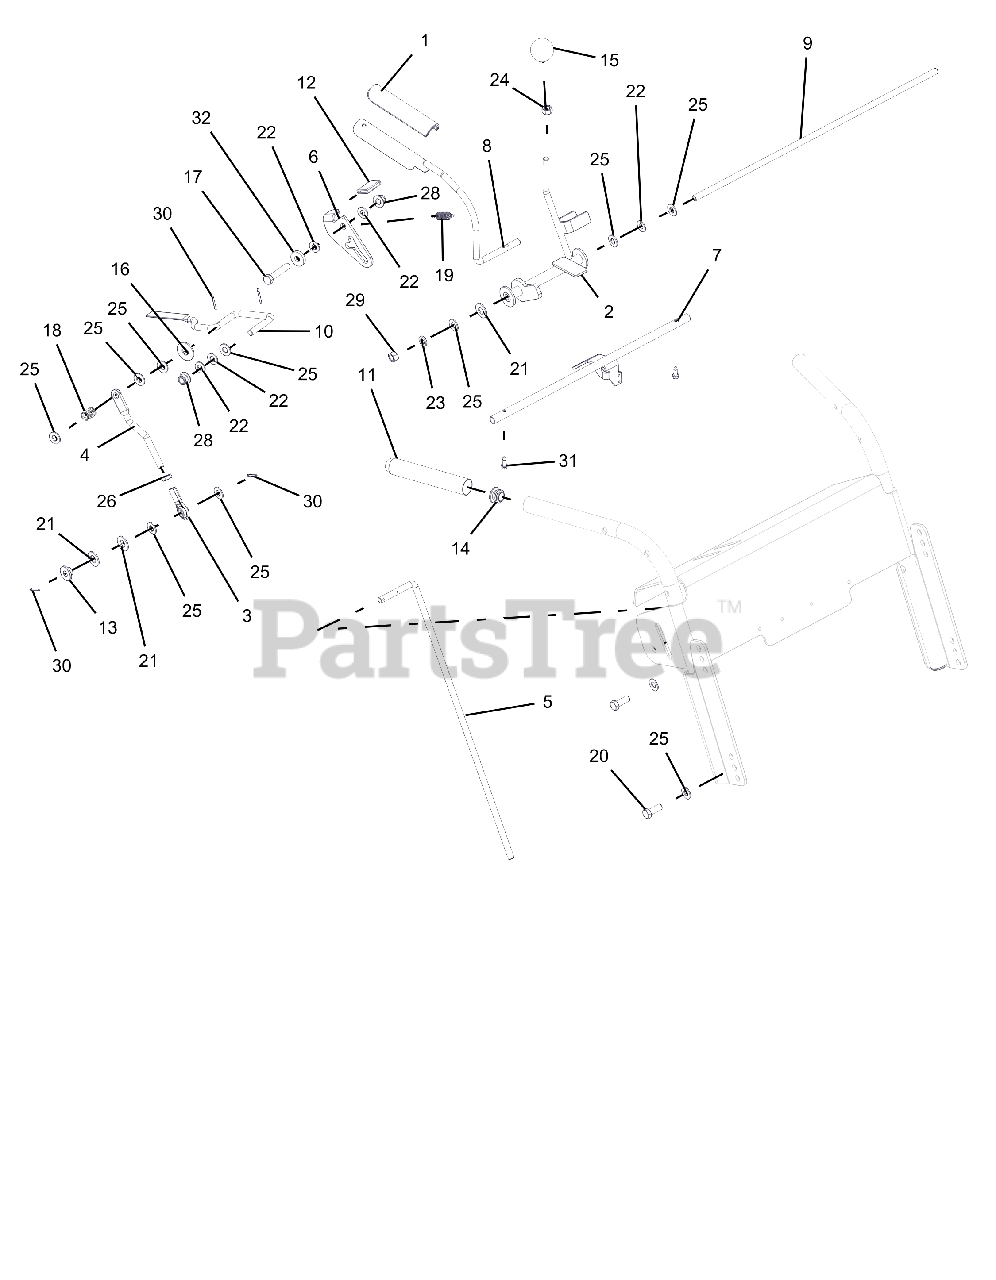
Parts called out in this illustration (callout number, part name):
1	GRIP, CLUTCH LEVER, LH AND RH
2	WELDMENT, RH LEVER
3	ROD END, .38 RH
4	ROD, STEERING LINK
5	ROD, SPD CONTROL
6	LATCH-RH THUMB
7	WLDMT, PIVOT TUBE-BLACK
8	WLDMT, LEVER RH OP MY14
9	ROD, SPEED CONTROL
10	LEVER, HAND CONTROL RH
11	GRIP, HANDLEBAR
12	GRIP, THUMB LATCH
13	BSHG-FLG .385X.500X.875X.31
14	CAPLUG, HANDLEBAR
15	KNOB,BALL -BLACK 1.47" .375-16
16	WSHR-FL-STL..50X1.25X.083 YWZ
17	BLT-HEX .38-16X2.00 GR5 YWZC
18	SPRG, COMPRESSION
19	SG-TENS .041X.500X1.750
20	BLT-HEX .38-16X1.00 GR5 YWZC
21	WSHR-FL-NYL .518X1.00X.08
22	WSHR-FL-NYL .375X.75X.060
23	WSHR-LK .38X.094 REG YWZC
24	NUT-HEX .38-16 YWZC
25	WSHR-FL-STL.406X.812X.065 YWZ
26	NUT-JAM .375-24 YWZC
28	NUT-LK-NYL-FLG .38-16 YWZC
29	NUT-HEX .375-24 YWZC
30	@PIN-CTR .09X.75 EXTPRSQCT YWZ
31	SCR-TAP 12-24X.625 HWH TYPE-F YWZC
32	WSHR-FL-STL .406X1.00X.188 YWZC
